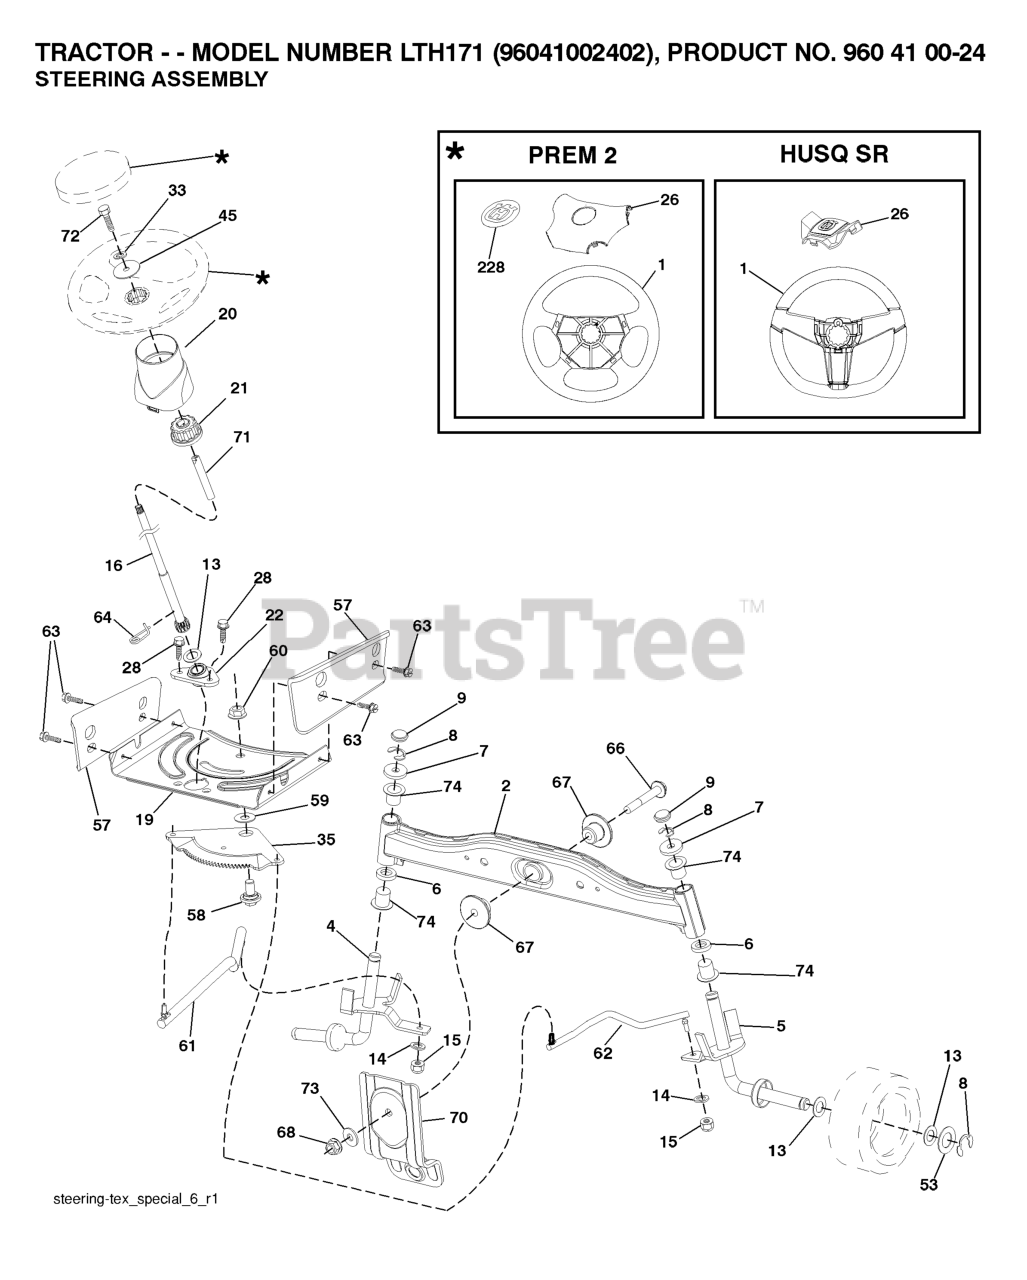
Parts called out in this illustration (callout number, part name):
1	RP WHEEL.STEER.HUSQ.PREM.OVMLD
2	AXLE.HALF.ASM.WELDED
4	SPINDLE.WELDED.LH.15"TEX
5	SPINDLE.WELDED.RH.15"T
6	THRUST WASHER
9	CAP.SPINDLE.BLACK
14	WASHER, LOCK 3/8
15	NUT CROWNLOCK 3/8-24
16	SHAFT STEERING
19	PLATE.STEER.DDL.NLT/NG
20	BOOT, STEERING
21	ADAPTER, WHEEL STNG..
22	BUSHING.ASM.STEERING.A
26	RP INSERT.CAP.WHL.STRG.HUSQ.
28	SCREW, 3/8-16X3/4
33	WASHER.LOCK.HVY.HLCL.SPR.5/16
35	GEAR.SECTOR.PLATE.DDL.
45	WASHER.11/32
53	WASHER.HARDENED
57	BRACKET.UPSTOP.TEX
58	BOLT.SHOULDER.SECTOR.P
59	WASHER.THURST.SECTOR.S
60	NUT FLANGE LOCK 5/8-11
61	DRAGLINK.LH.BALLSTUD.D
62	DRAGLINK.RH.BALLSTUD.D
63	SCREW
64	RETAINER.CLIP.SPRING.S
66	BOLT HEX FGHD 7/16-14 X 3 SERR
67	BUSHING.PM.FRONT AXLE
68	NUT.LOCK.FLANGE.7/16
70	BRKT.DECK.SUSPENSION.F
71	SHAFT EXTENSION STEERING
72	BOLT YT
73	WASHER.1.5X.505X.118
74	BRNG T
228	DECAL.WHEEL.STRG.LGN.H
